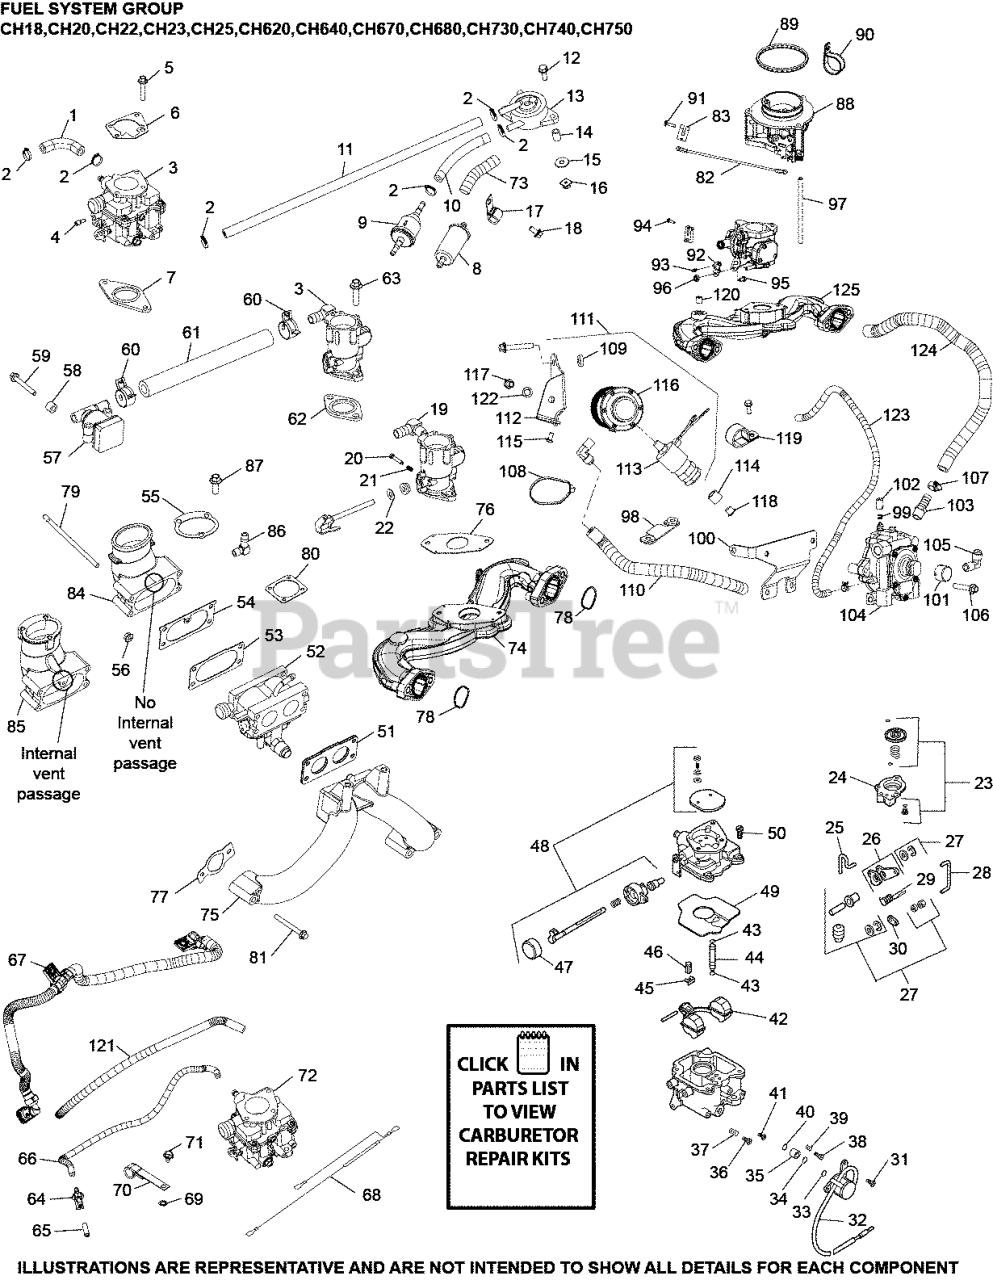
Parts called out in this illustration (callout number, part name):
1	HOSE,LW PERM.FUEL 24.00"-USE 25 111 81-S
2	CLAMP, HOSE (KM)-USE 25 237 31-S
3	KIT,CARB(KEIHIN) W/GASKETS KSF
5	SCREW, FLG M6X1.0X30
7	GASKET, CARBURETOR
9	FILTER, FUEL
64	CONNECTOR, EVAPORATIVE
65	CAP, MASKING
66	HOSE, EVAPORATIVE 20" USE 24 326 143-S
75	MANIFOLD, METAL INTAKE
77	GASKET, INTAKE MANIFOLD USE 24 041 79-S
81	SCREW, FLG M6X1.0X55
